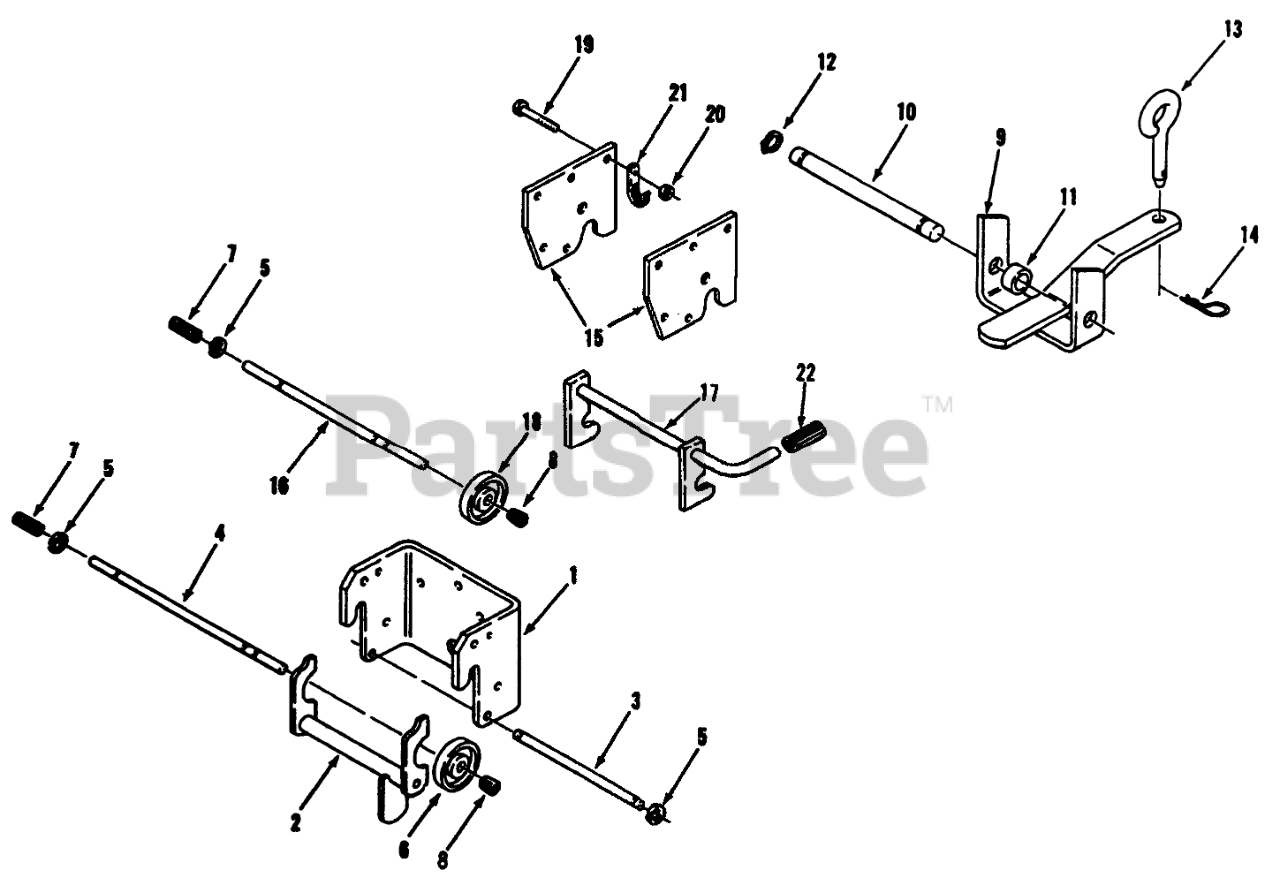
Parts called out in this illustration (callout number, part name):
1	Front Hitch
2	Assy-Latch
3	ROD-LATCH PIVOT
4	ROD-LOCK
5	RING-RETAINING
7	SPRING
8	CAP-ROD, PLUNGER
9	Hitch
10	PIN-STATIONARY HITCH
11	Spacer
12	E-RING
13	PIN-TOOL
14	Hairpin Cotter
15	Hitch Plate
16	ROD-LOCK
17	MID HITCH ASM
19	SCREW-HH
21	CLIP
22	GRIP
